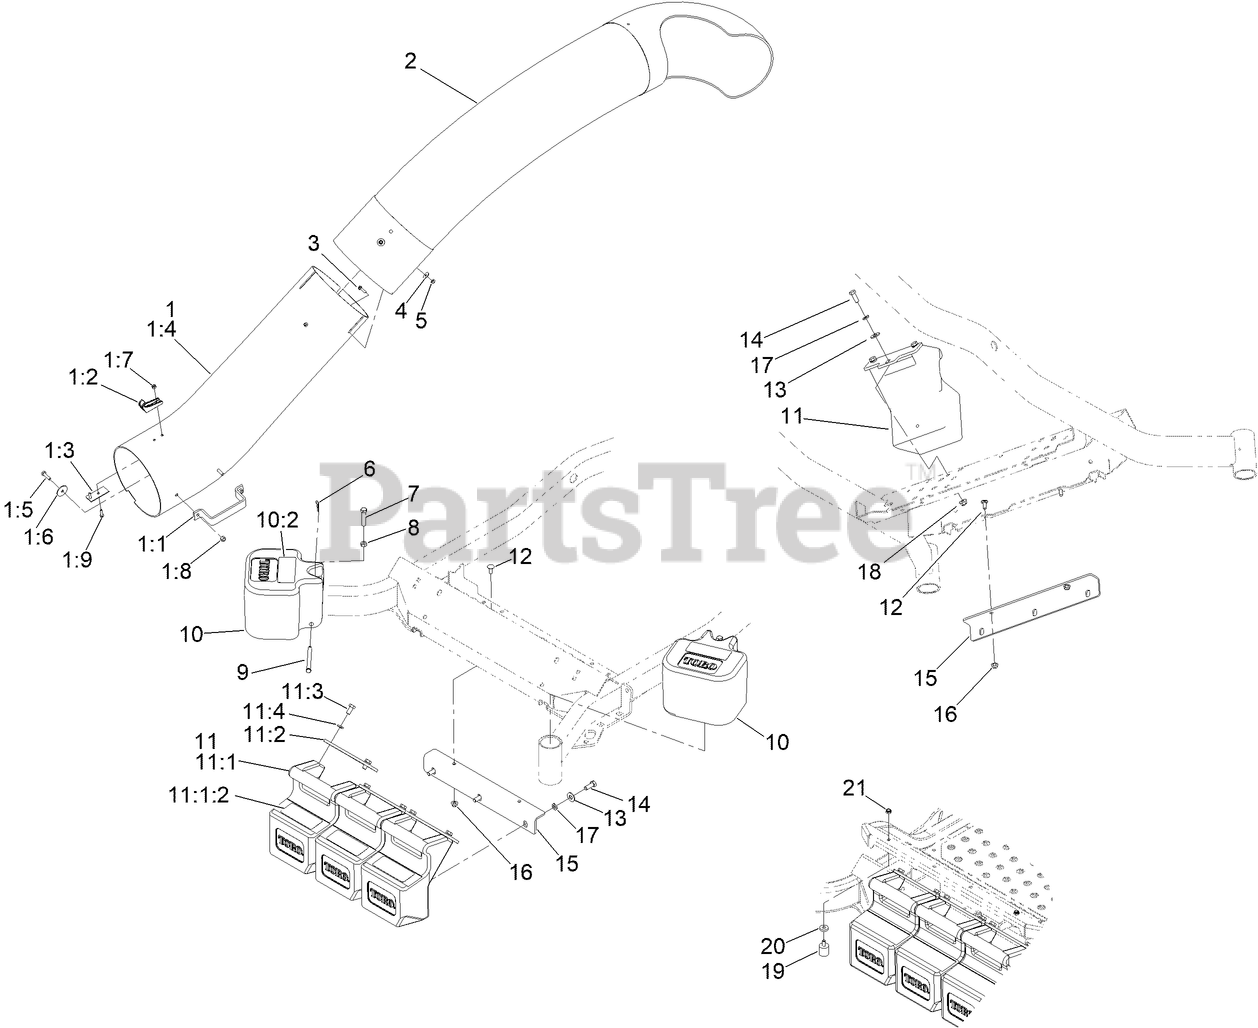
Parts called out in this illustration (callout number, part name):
1	LOWER TUBE ASM
1:2	LATCH-CATCH
1:3	PLATE-BACKING
1:4	TUBE-LOWER
1:5	SCREW-HH
1:6	WASHER-FLAT
1:7	NUT-LOCK, NI
1:8	NUT-LOCK, NI
1:9	SCREW-HWH
2	TUBE-UPPER
3	SCREW-HWH
4	WASHER-FLAT
5	NUT-LOCK, NI
6	PIN-COTTER
7	SCREW-HH
8	NUT-HEX
9	PIN-CLEVIS
10	WEIGHT 62 LBS ASM W/DECAL
10:2	DECAL-WARNING, COUNTERWEIGHT
11	WEIGHT ASM
11:1	WEIGHT W/DECAL ASM
11:1:2	DECAL-WARNING, COUNTERWEIGHT
11:2	TAB-SUPPORT, WEIGHT
11:3	SCREW-HH
11:4	WASHER-LOCK
12	SCREW-CARR
13	WASHER-FLAT
14	SCREW-HH
15	BRACKET-MOUNT, WEIGHT
16	NUT-HF, NI
17	WASHER-LOCK
18	NUT-HF, NI
19	BUMPER-RUBBER
20	SPACER
21	NUT-LOCK, NI
